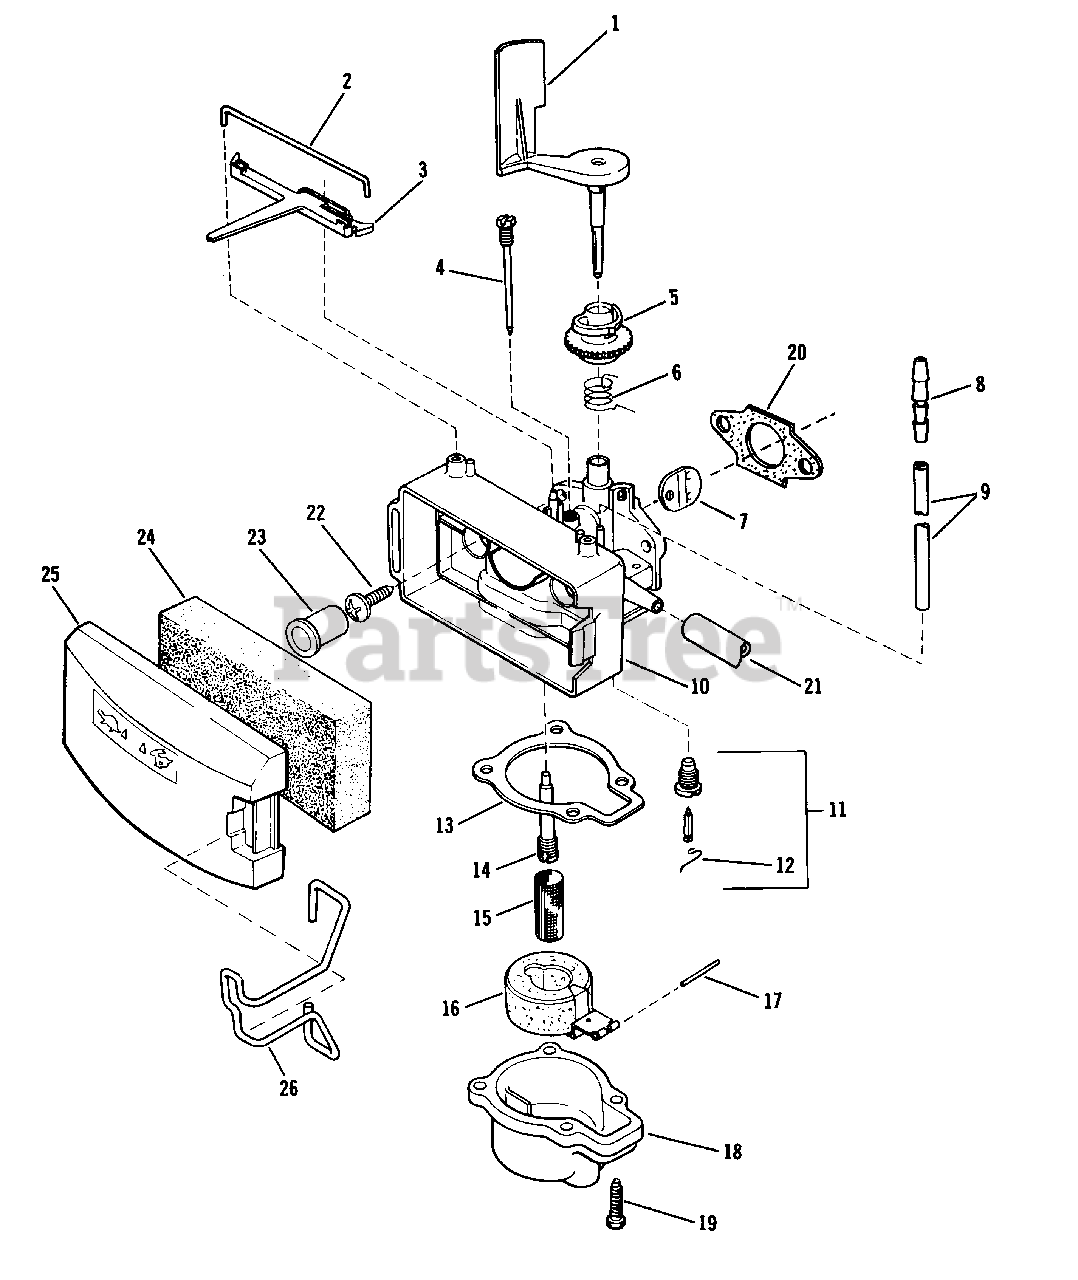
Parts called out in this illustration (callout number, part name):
1	Air Vane and Shaft
2	Retainer-Speed Control Lever
3	Speed Control Lever
4	Needle Adj. Assembly
5	Collar
6	Spring
7	Disc-Throttle
8	Connector-Reducer
9	Tube-Primer
10	Carburetor Body
11	Float Valve and Seat Assembly
12	Clip
13	Gasket
14	Nozzle
15	Filter-Carburetor
16	Float and Arm Assembly
17	Pin-Float
18	Float Chamber
19	Screw-Float Chamber
20	Gasket-Carb. to Crankcase Cover
21	Fuel Line
22	Screw-Carburetor Mounting
23	Plug
24	Element-Air Filter
25	Cover-Air Filter
26	Retainer-Filter Cover
